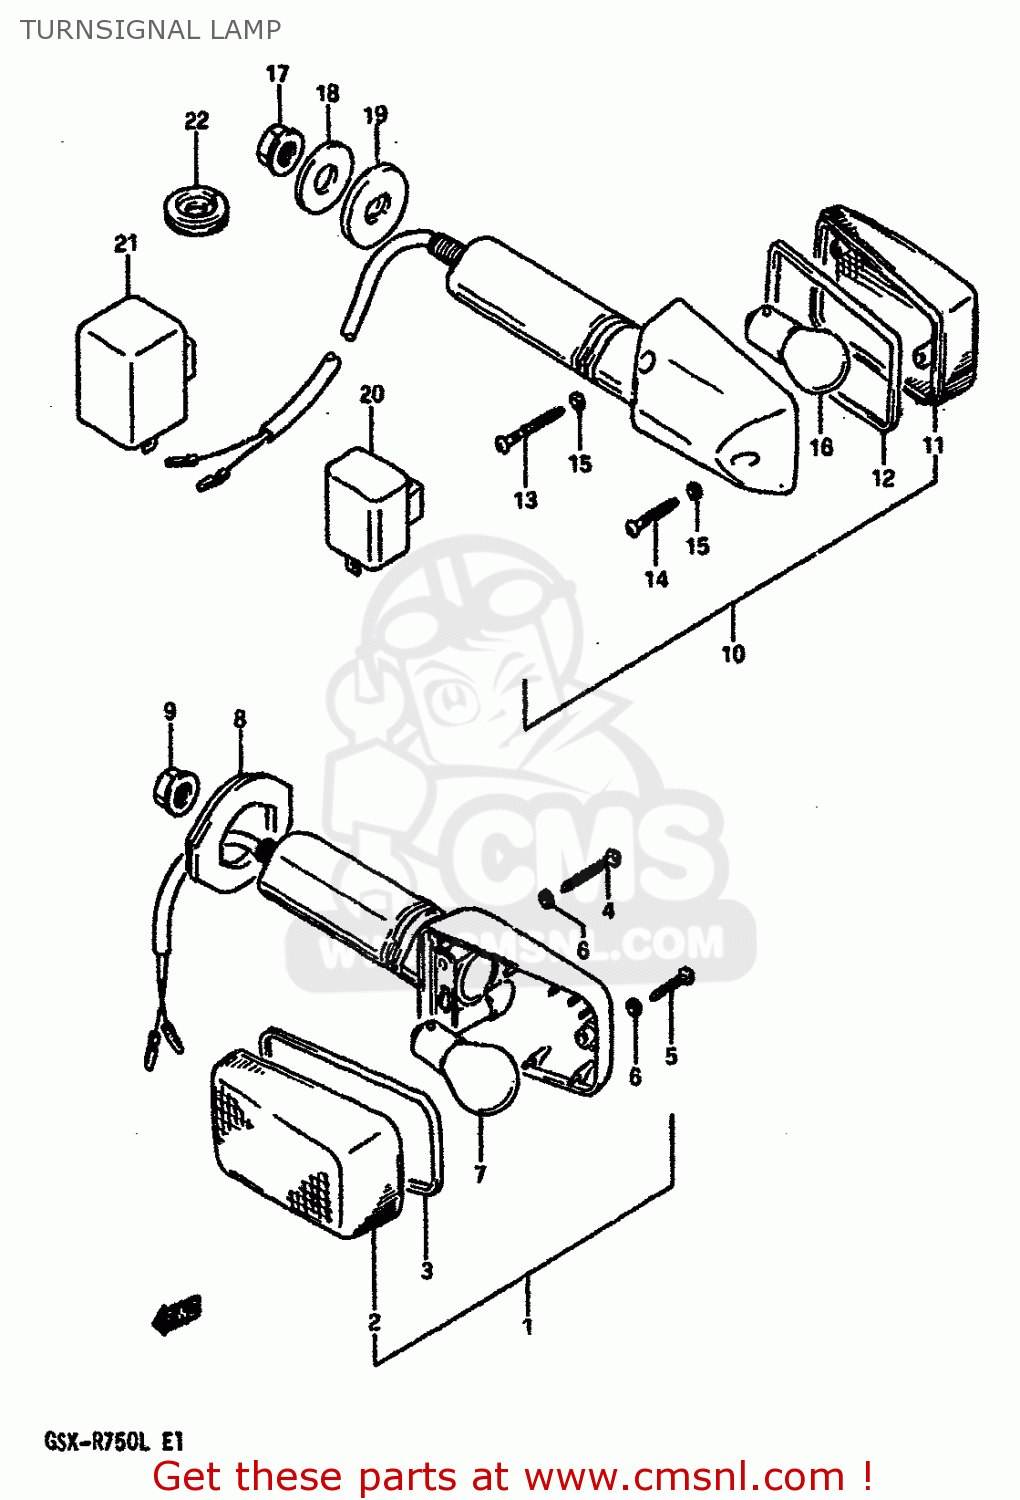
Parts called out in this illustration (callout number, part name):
1	LAMP ASSEMBLY,FRONT TURN SIGNAL
2	LENS
3	GASKET (NAS)
4	SCREW(3X30)
5	SCREW
6	GASKET (NAS)
7	BULB(12V21W)
8	GROMMET
9	NUT
10	LAMP ASSY,RR TURNSIGNAL
11	LENS
12	GASKET (NAS)
13	SCREW(3X30)
14	SCREW
15	GASKET (NAS)
16	BULB(12V21W)
17	NUT
18	WASHER(10.5X30X3.2)
19	SPACER,RR TURNSIGNAL
20	RELAY ASSEMBLY,TURN SIGNAL
21	RELAY ASSEMBLY,TURN SIGNAL
22	GROMMET
